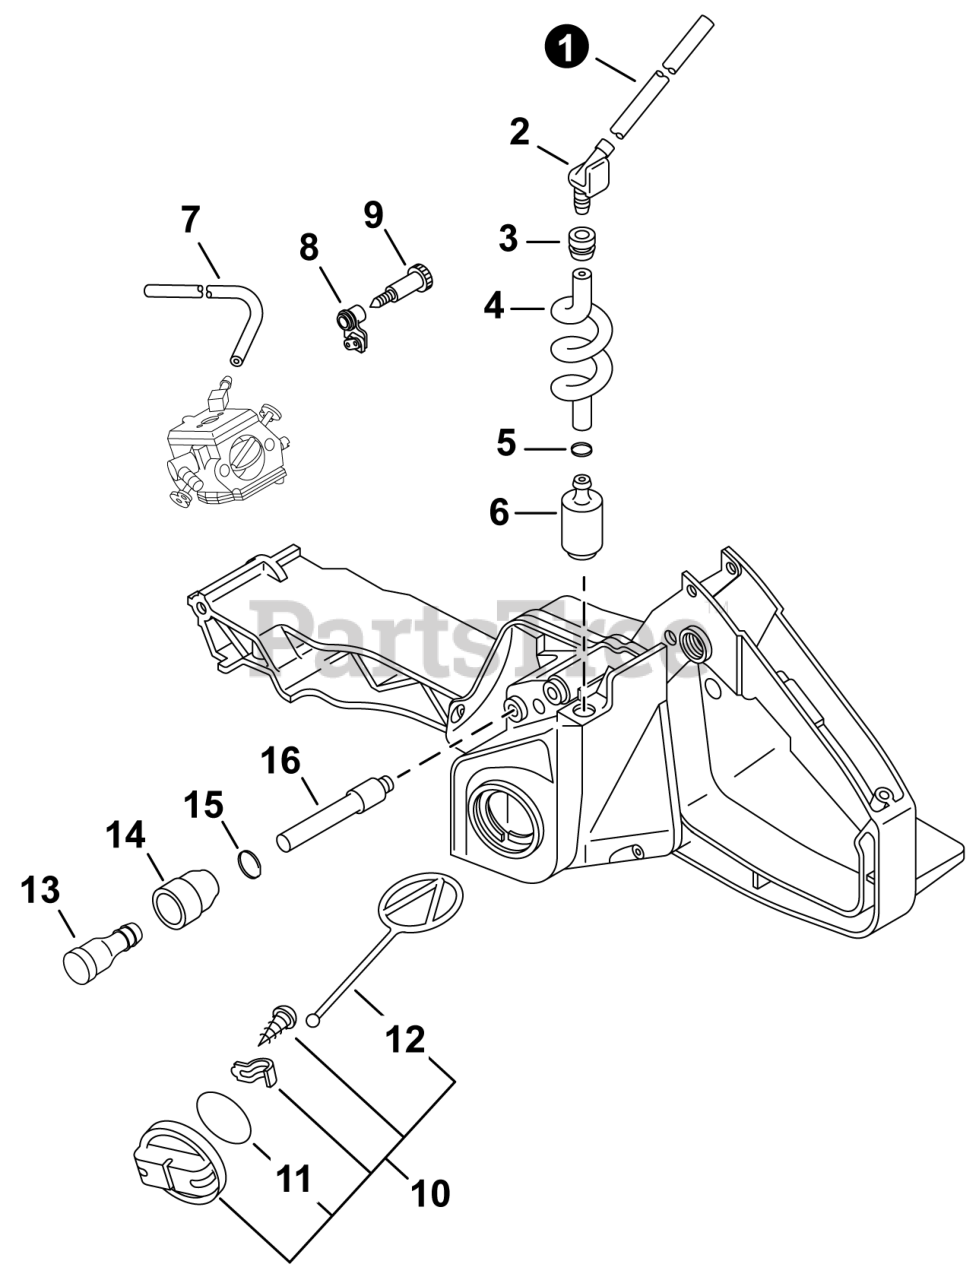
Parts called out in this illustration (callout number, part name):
1	PIPE, FUEL 3×6×120 BLACK
2	CONNECTOR, PIPE
3	GROMMET
4	PIPE, FUEL
5	CLIP Ø6.5 MM
6	FILTER, FUEL
7	PIPE, IMPULSE 3×6(8)×160
8	GROMMET, NEEDLE
9	SCREW, IDLE ADJUST - ORANGE
10	CAP ASSY, FUEL
11	O-RING 29
12	FUEL CAP CONNECTOR (L=60MM)
13	VENT ASSY
14	HOLDER, VENT
15	CLIP 5.5
16	PIPE 3×5×90
